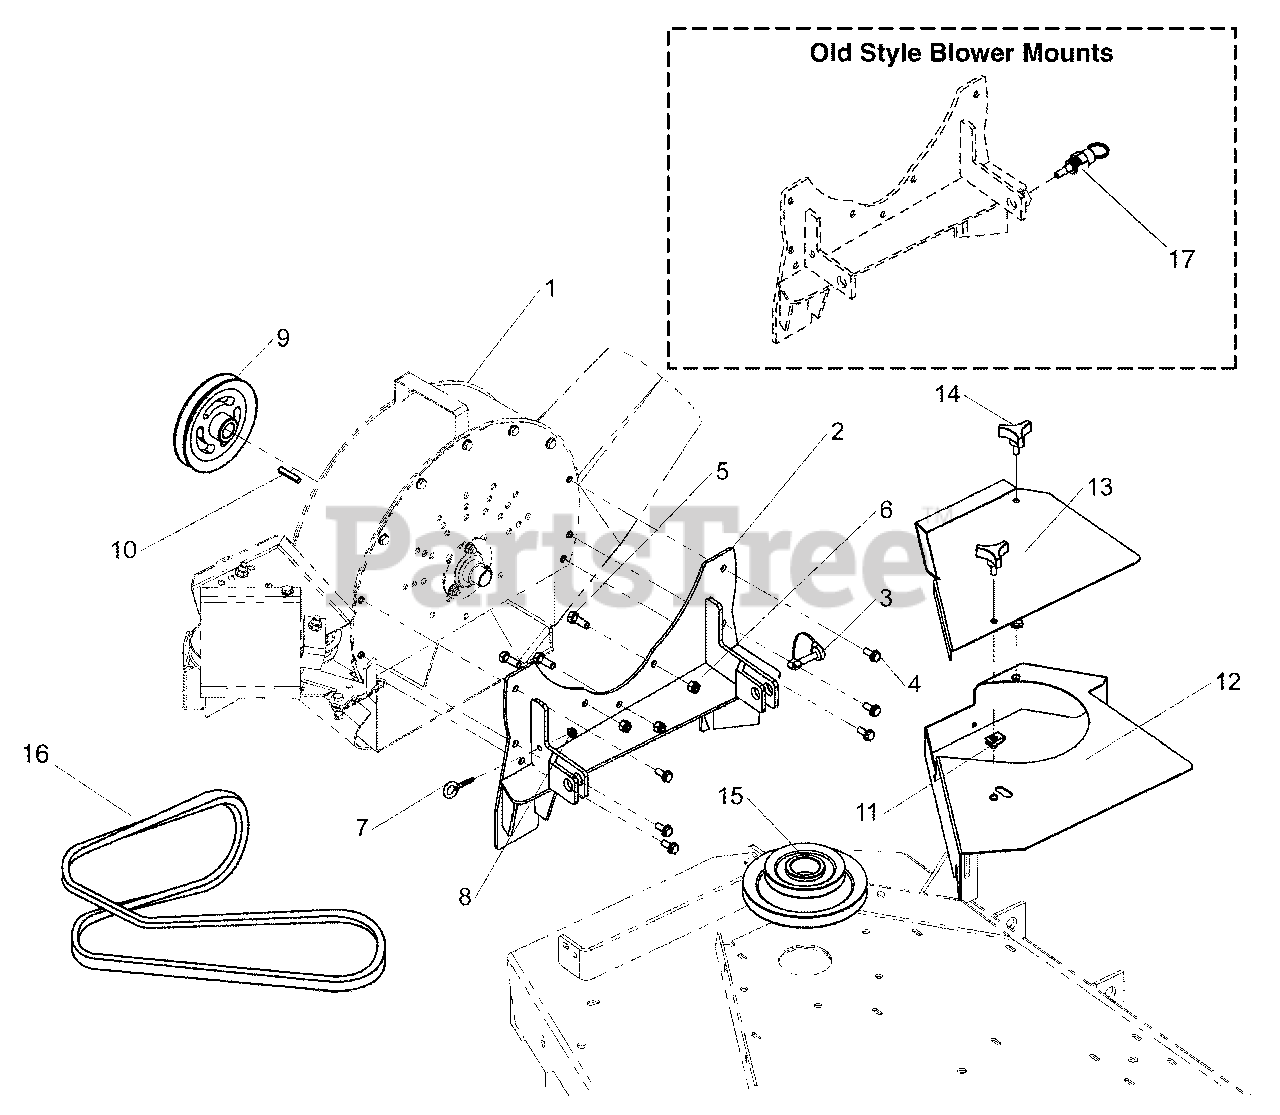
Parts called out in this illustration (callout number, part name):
1	BLOWER ASSEMBLY
2	WELD, BLOWER MOUNT, 48" - BLACK
2	WELD, BLOWER MOUNT, 52" - BLACK
2	WELD, BLOWER MOUNT, 61" - BLACK
2	WELD, BLOWER MOUNT, 52" - BLK
3	SNAPPERPIN, 5/16 x 2"
4	BOLT, 5/16-18 x 3/4" SELF LOCK
5	BOLT, 3/8-16 x 1" GD5
6	NUT, 3/8-16 HEX NYLON LOCK
7	EYE BOLT, 1/4-20 x 2"
8	NUT, 1/4-20 HEX NYLOCK FLANGE (5025391)
9	PULLEY
10	KEY 1/4 SQ x 1-1/2 LONG
11	BODY CLIP 5/16-18 x 1/2" DEEP
12	WELD, GUARD DECK
13	BELT SHIELD
14	KNOB, PLASTIC, 5/16-18 x 3/4"
17	PIN, SPRING LOADED
